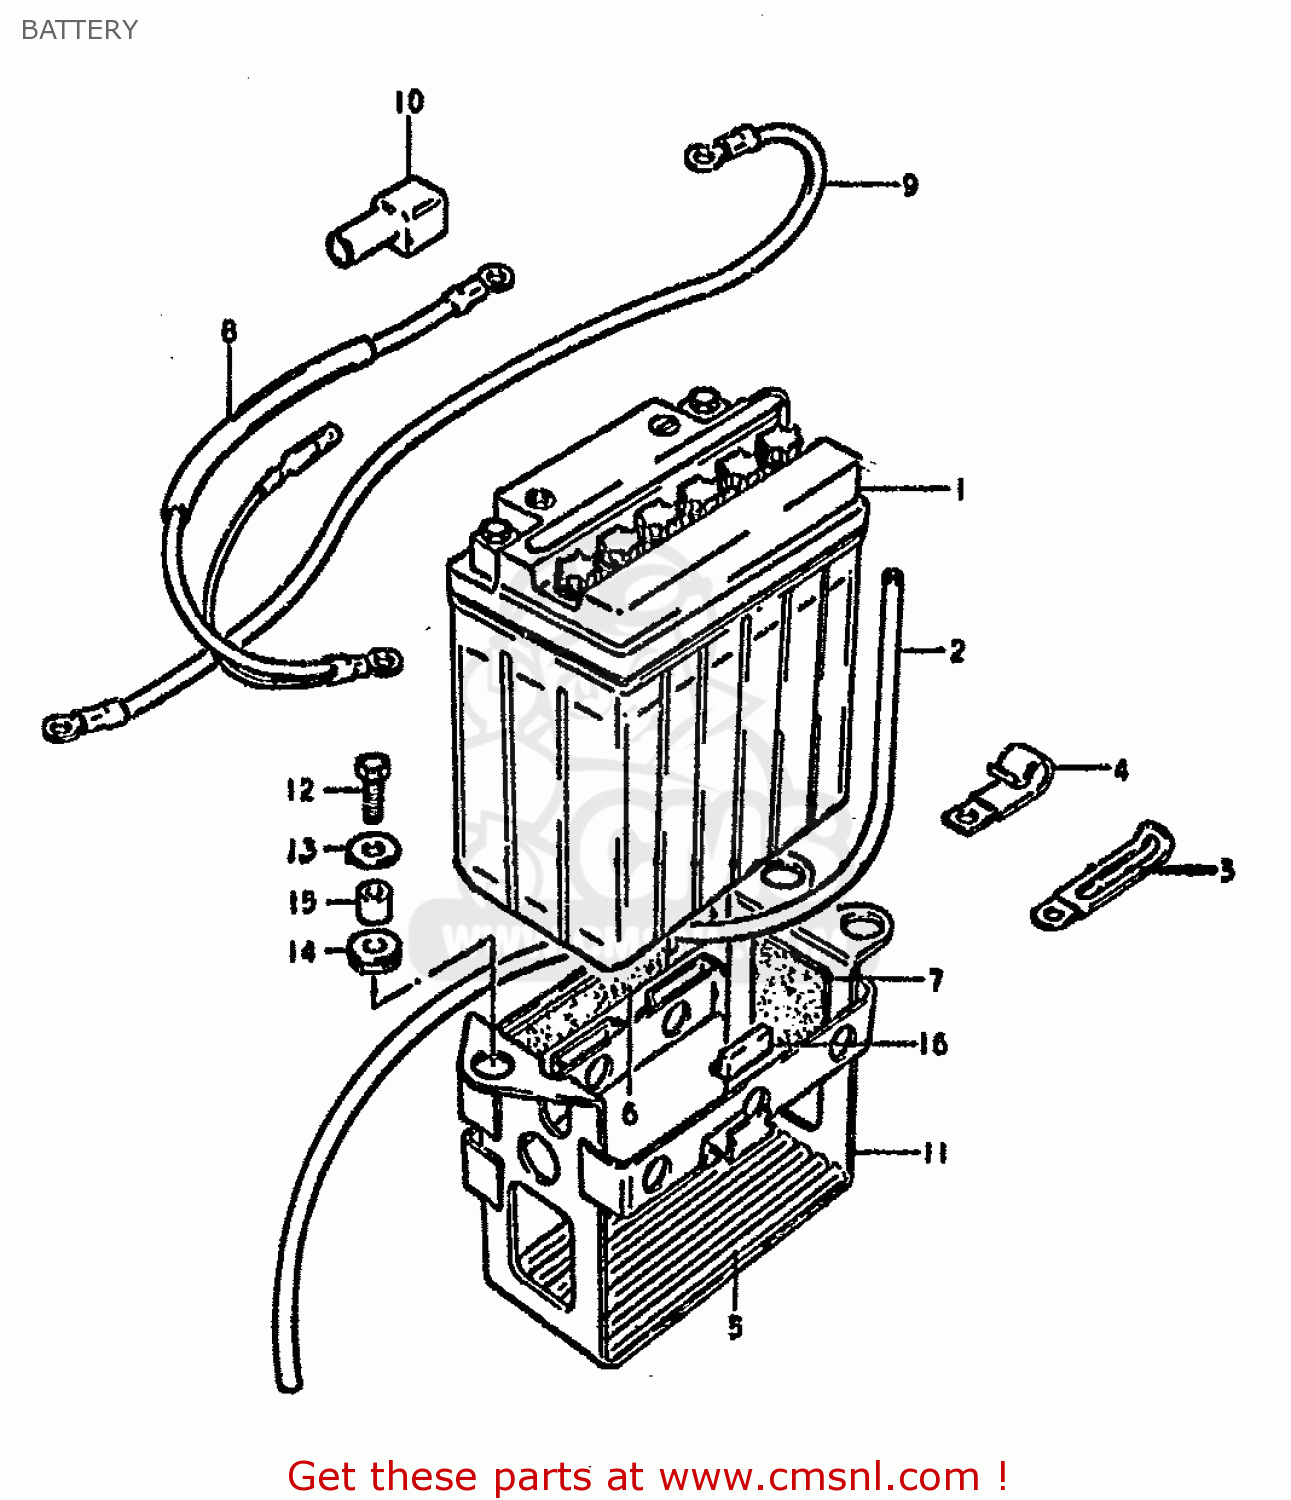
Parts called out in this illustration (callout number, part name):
1	BATTERY ASSY (12V)
2	HOSE,BATTERY EXHAUST
3	CLAMP L:35
4	CLAMP
5	PROTECTOR,BATTERY
6	PROTECTOR(20X90)X4
7	PROTECTOR,BATTERY
8	WIRE,BATTERY PLUS
9	LEAD WIRE,BATTERY(-)
10	CAP,TERMINAL
11	HOLDER,BATTERY
12	BOLT, UPPER
13	WASHER
14	CUSHION
15	SPACER(6.1X9X7.5)
16	CUSHION,FRAME COVER
